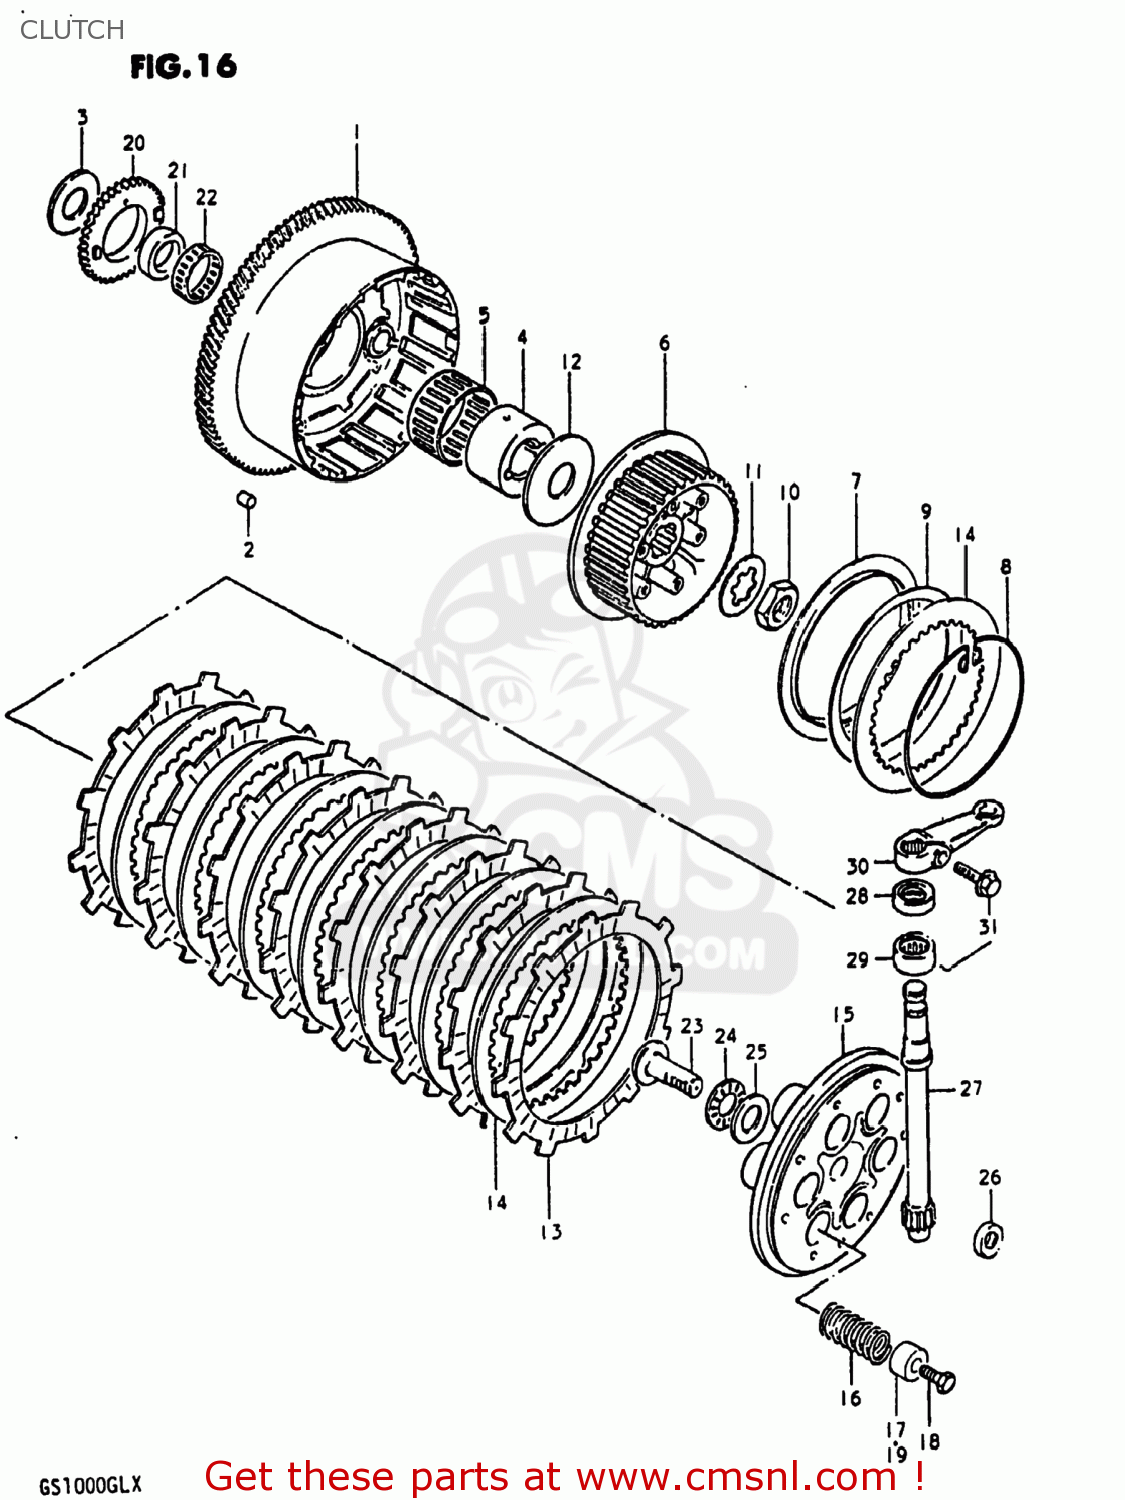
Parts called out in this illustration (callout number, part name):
1	GEAR ASSEMBLY,PRIMARY DRIVE
2	CUSHION,PRIMARY DRIVEN GEAR
3	WASHER
4	SPACER,PRIMARY DRIVEN
5	BEARING
6	HUB,CLUTCH SLEEVE
7	SEAT,WAVE WASHER
8	RING,STOPPER
9	WASHER
10	NUT
11	WASHER,LOCK
12	WASHER(25X66X3.5)
13	PLATE,CLUTCH DRIVE (MCA)
14	PLATE,CLUTCH DRIVEN (NAS)
15	PLATE,CLUTCH PRESSURE
16	SPRING
17	SPACER
18	BOLT
19	WASHER
20	GEAR,OIL PUMP DRIVE
21	SPACER,OIL PUMP DRIVE GEAR
22	BEARING(36X40X10)
23	RACK,CLUTCH RELEASE
24	BEARING(15X28X2)
25	WASHER
26	SEAL,OIL(10X16X5)
27	PINION,CLUTCH RELEASE
28	OIL SEAL
29	BEARING(15X22X12)
30	ARM,CLUTCH RELEASE
31	BOLT,REAR
